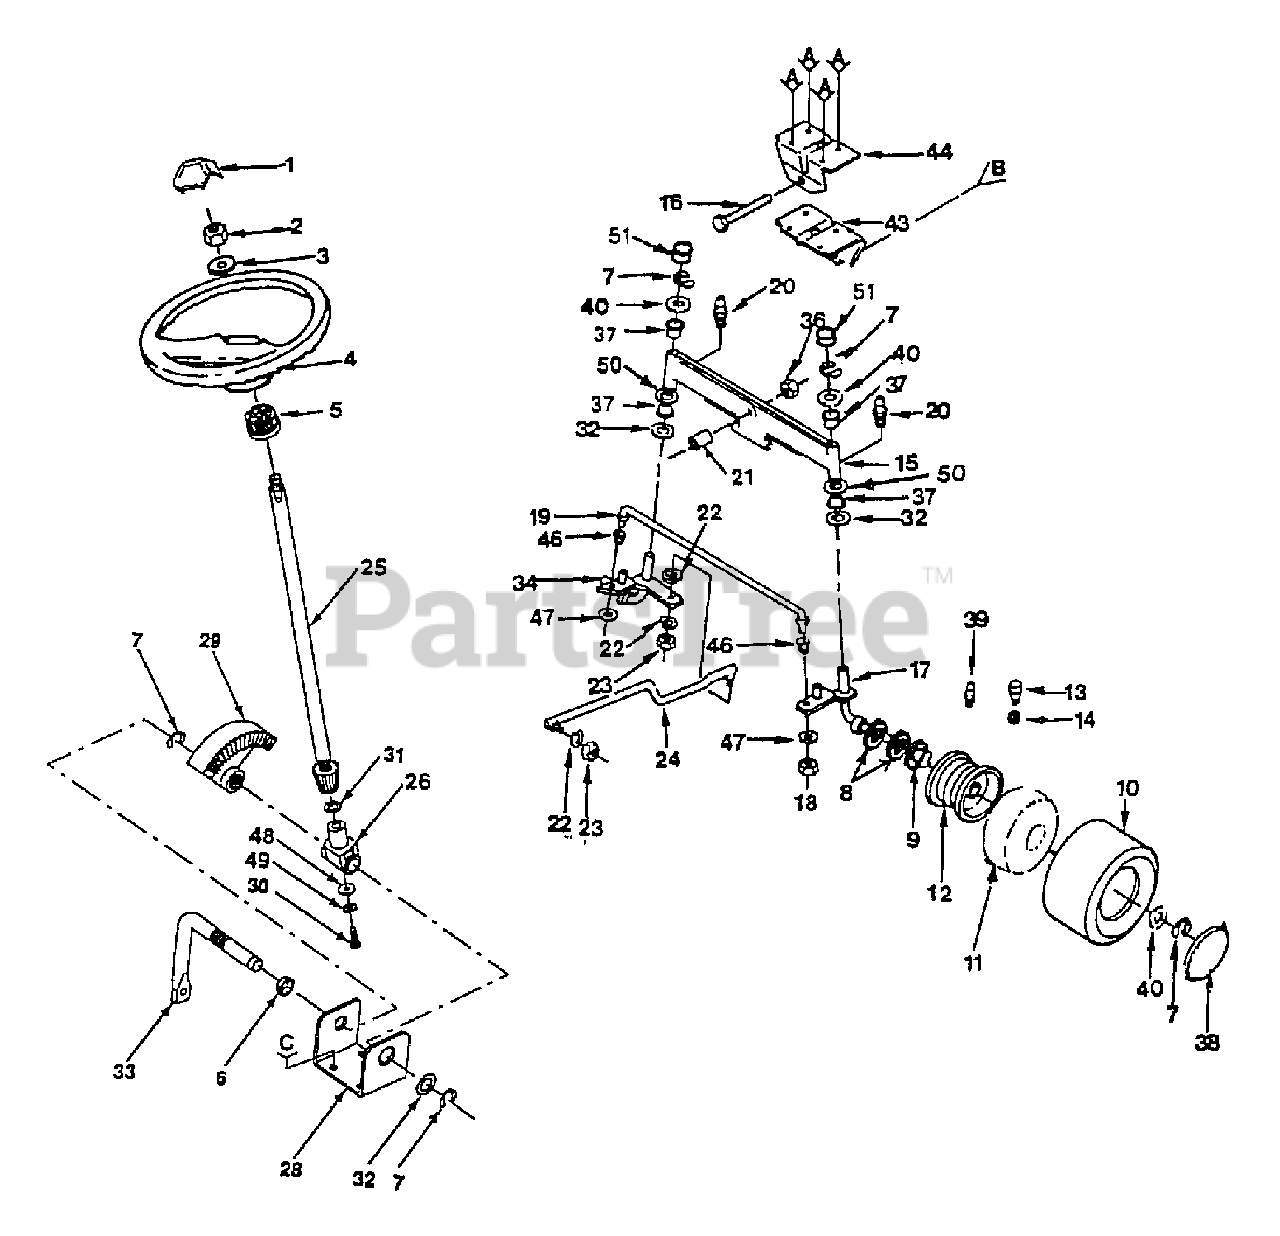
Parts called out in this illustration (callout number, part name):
1	Insert, Steering Wheel
2	Nut, Hex, Jam, Toplock 1/2-20
3	Washer 17/32 x 2-1/4 x .160
4	Wheel, Steering
5	Adapter, Steering Wheel
6	Nyliner, Snap In
7	Ring, Klip
8	Washer 25/32 x 1-1/4 x 16 Gauge
9	Bearings, Wheel, Front
10	Tire, Front
11	Tube, Tire
12	Rim Assembly, Front
13	Stem, Valve
14	Cap, Valve
15	Axle Assembly, Front
16	Bolt, Hex 5/8-11 x 3-3/4
17	Spindle Assembly, R.H.
18	Nut, Hex, Nylon 5/16-24 UNF
19	Rod, Tie
20	Fitting, Grease
21	Spacer, Bearing, Front Axle
22	Lock washer 3/8
23	Nut, Hex 3/8-24
24	Link, Drag
25	Shaft, Steering
26	Support Shaft
28	Bracket Assembly, Steering
29	Gear, Sector
30	Screw, Socket Hex 1/4-20 x 5/8
32	Thrust, Bearing
33	Shaft, Pitman
34	Spindle Assembly, L.H.
36	Nut, Flange 5/8-11
37	Bearing
38	Cover, Wheel
39	Fitting, Grease
40	Washer 25/32 x 1-5/8 x 16 Gauge
43	Support, Saddle, Front
44	Support, Saddle, Rear
46	Washer 11/32 x 3/4 x 16 Gauge
47	Washer, Lock Heavy Helical Spring
48	Washer, Shim 1/4 x 5/8 x .062
49	Washer, Lock 1/4
50	Washer 27/32 x 1-1/4 x 16 Gauge
51	Cap, Spindle
